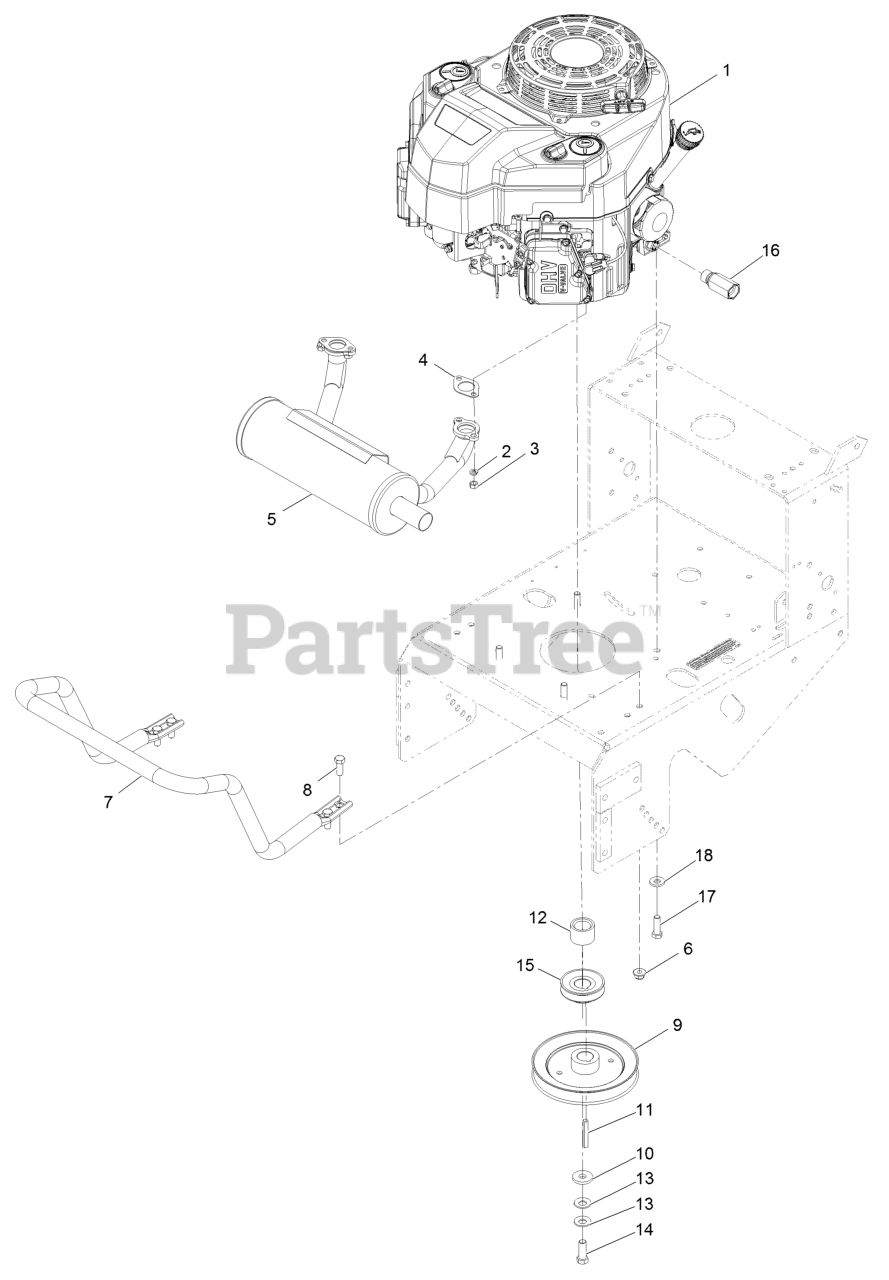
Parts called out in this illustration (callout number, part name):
1	Engine-Kawasaki
2	Washer-Lock
4	Gasket-Exhaust
5	Muffler-Horizontal, Offset
6	Nut-HF, NI
7	Guard-Muffler
8	Screw-HH
9	Sheave
12	Spacer-Clutch
13	Washer-Spring
14	Screw-HH
15	Sheave-Transmission
16	Adapter
17	Screw-HH
18	Washer-Belleville
